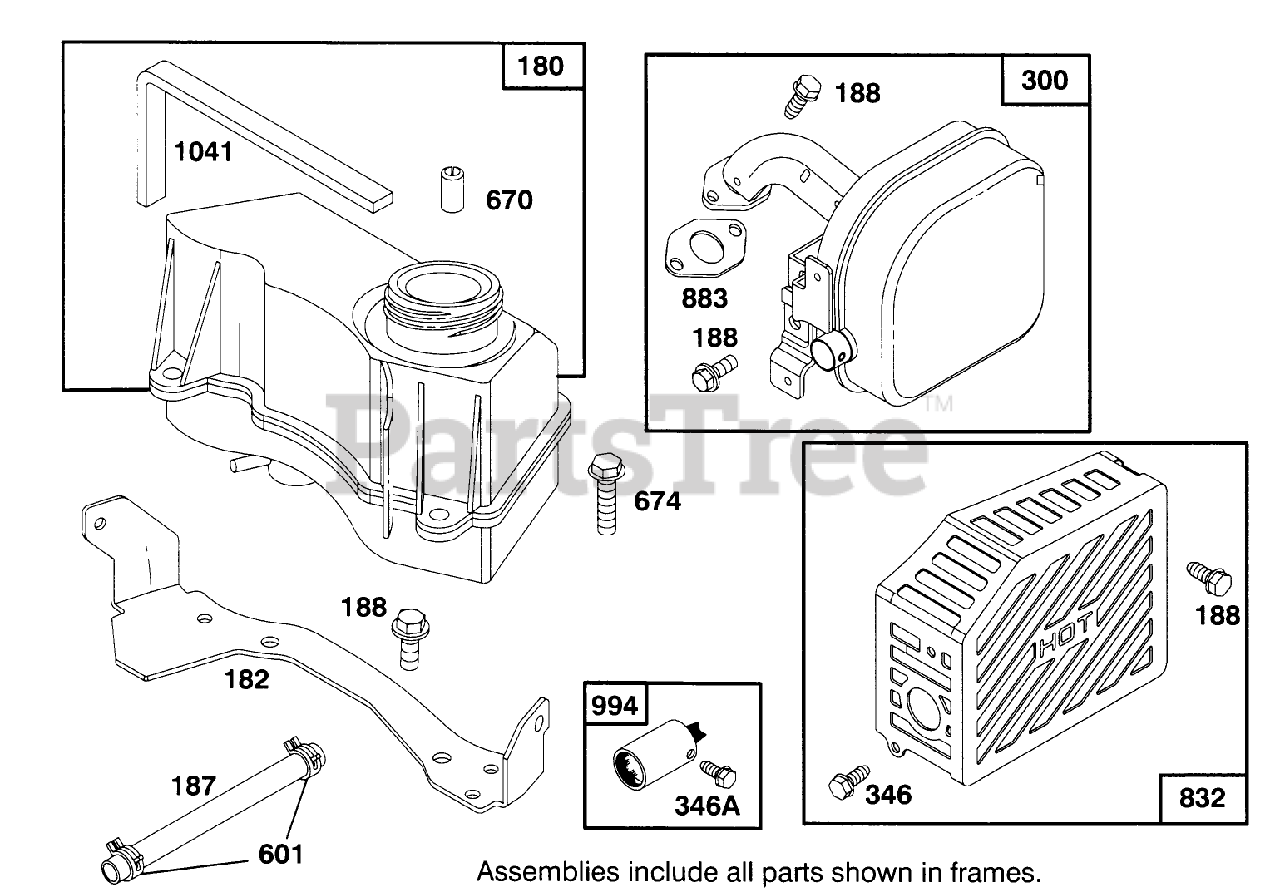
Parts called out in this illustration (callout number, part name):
300	MUFFLER - EXHAUST
601	CLAMP - CL PIPE
670	SPACER
674	SCREW - HEX HEAD
